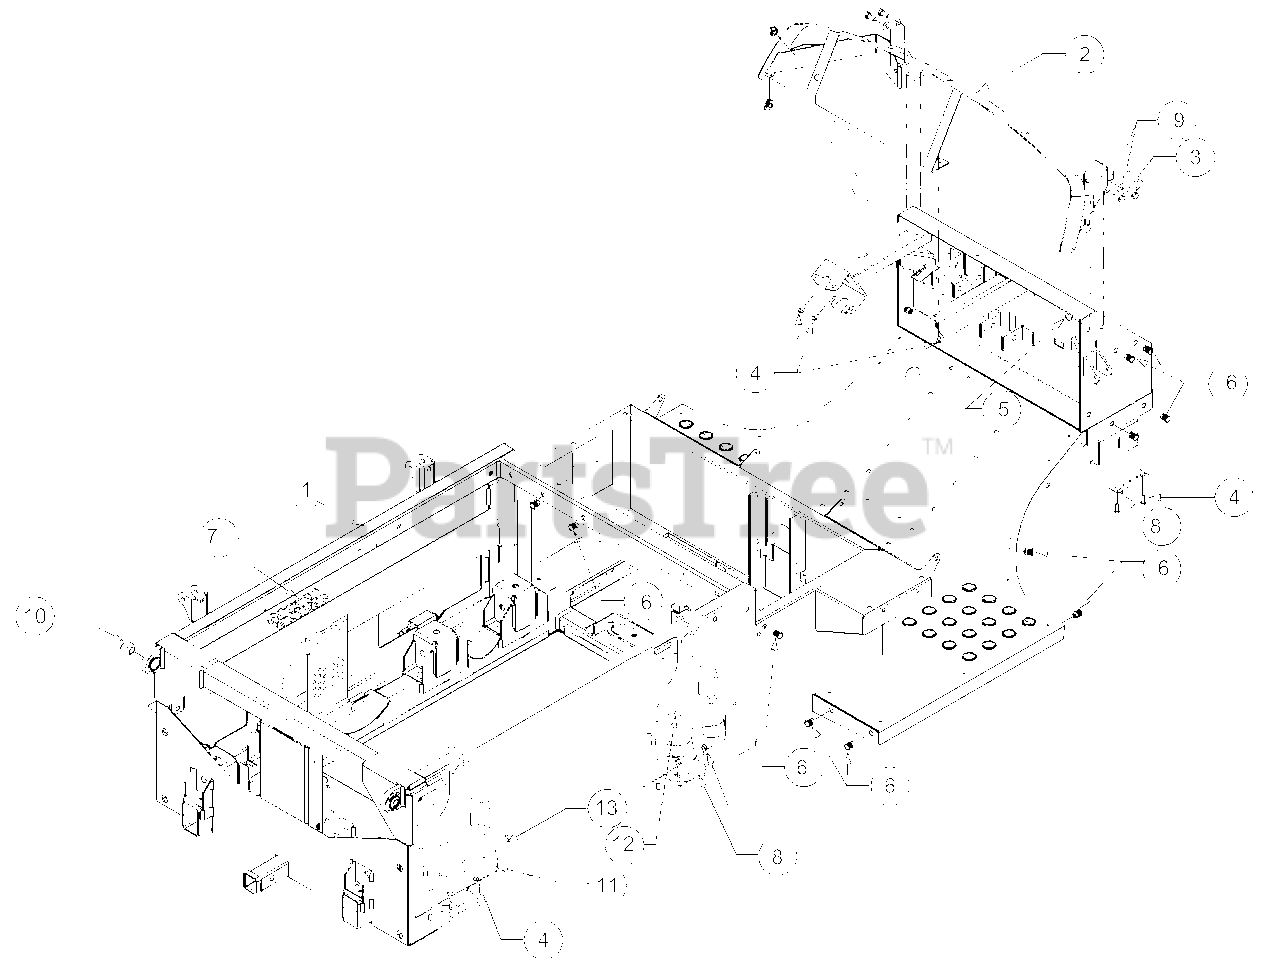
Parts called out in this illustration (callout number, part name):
1	Frame Assembly, Complete
3	Screw, Hex, 3/8-16 x .75
4	Screw, Self-tapping, 1/4-20 x 0.500
5	Nut, Flange Lock, 3/8-16
6	Nut, Insert, 5/16-18
7	Chain, 60-97 Pitch
8	Bumper, Compression Extension
9	Washer, Flat, .406 x 812 x .51
10	Rubber Bushing, Bed Pivot
12	Nut Hex, Flange Lock
13	Plate, Spacer
